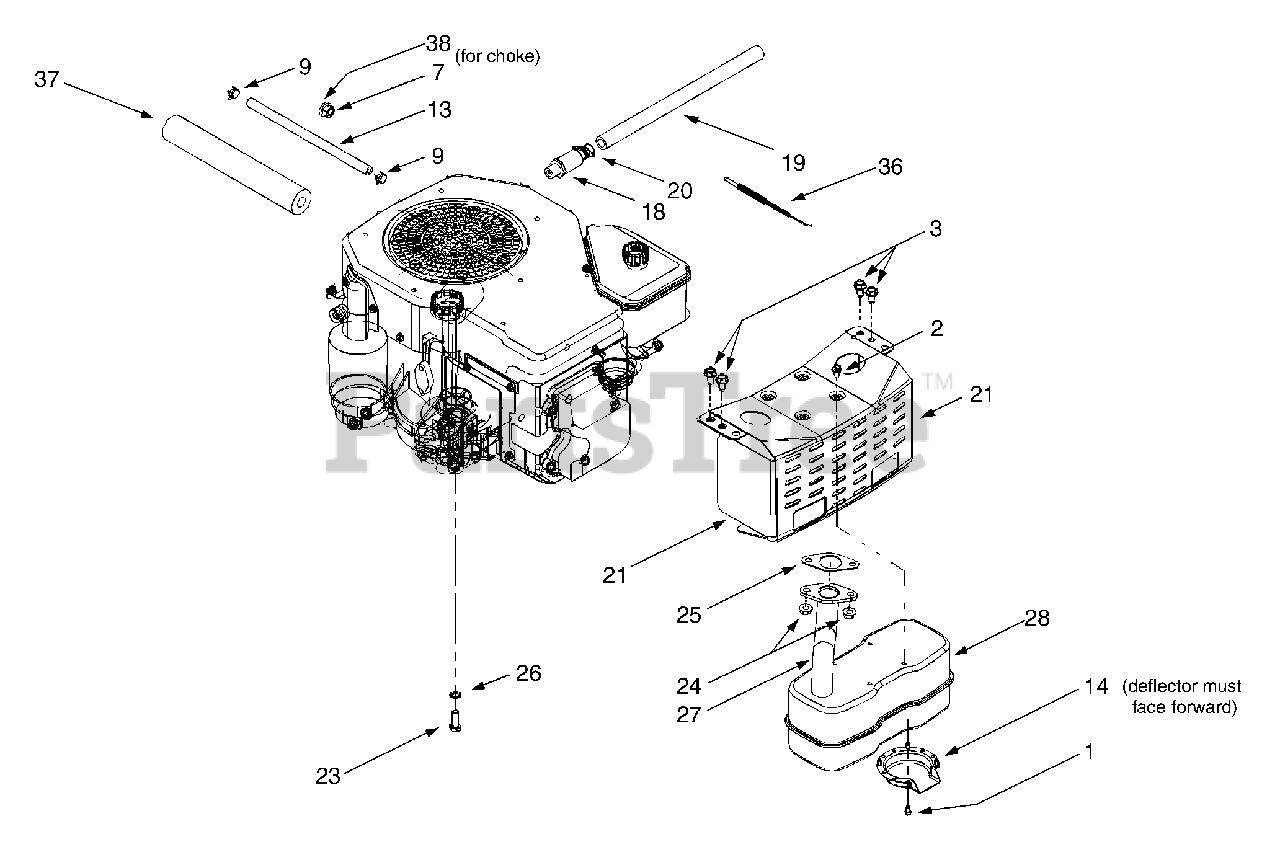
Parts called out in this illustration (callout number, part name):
1	Self-tapping Screw, #8-32 x .375
2	Self-tapping Screw, 1/4-20 x .5
3	Self-tapping Screw, 5/16-18 x .625
7	Hex Nut, 3/8-16
9	Hose Clamp
13	Fuel Line Hose
14	Muffler Deflector
18	Oil Drain Valve
19	Oil Drain Hose
20	Oil Drain Cap
23	Hex Cap Screw, M8-1.25 x 25
24	Flange Nut, M8-1.25
25	Exhaust Gasket
26	External Lock Washer, 5/16
27	Exhaust Pipe
28	Muffler, Single Inlet
36	Throttle Cable
37	Foam
38	Flat Washer, .406 x .875 x .059
